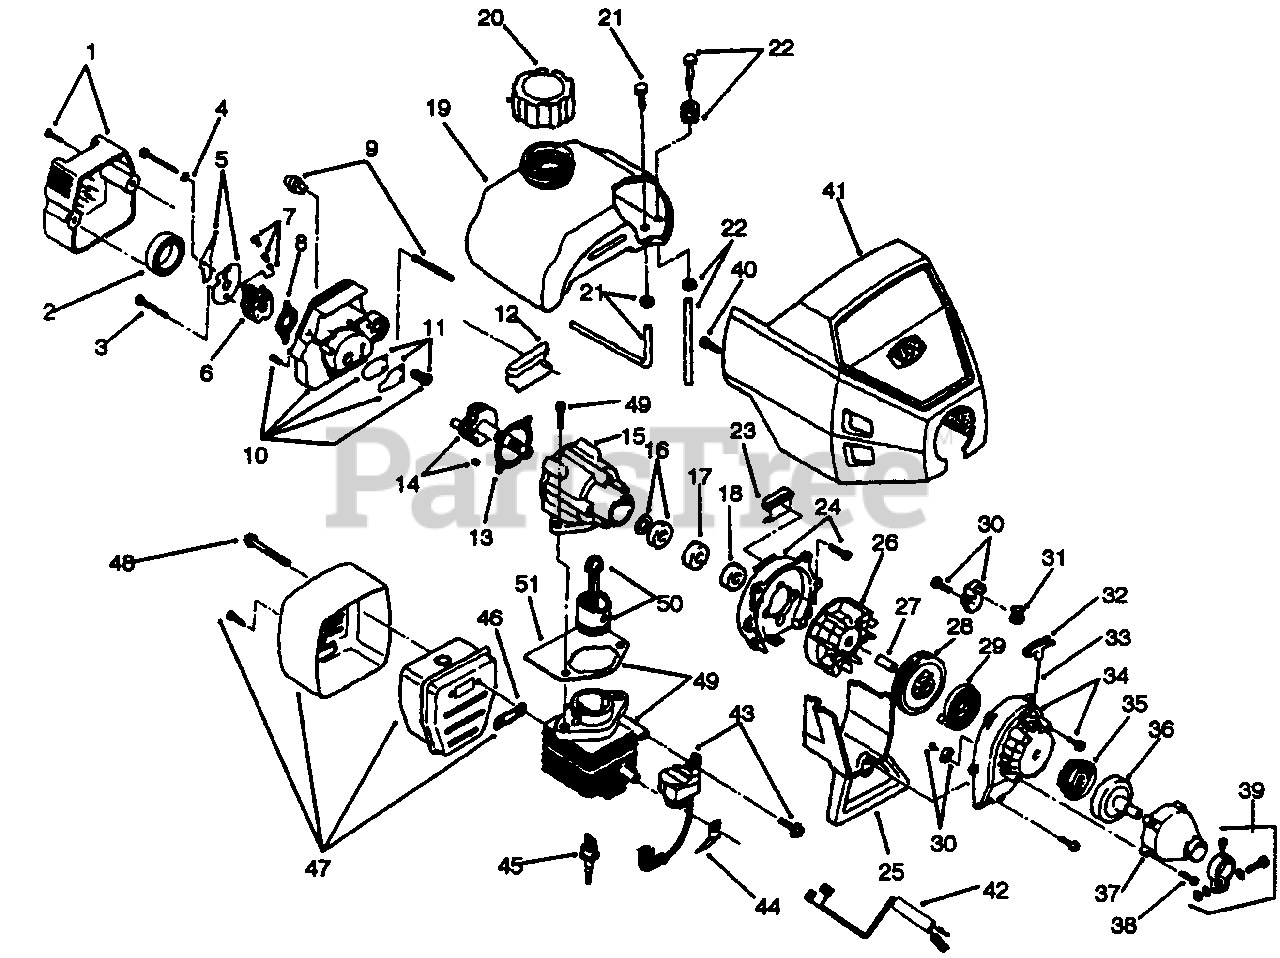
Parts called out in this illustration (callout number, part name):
1	Assy.-Carburetor/Air Clean (Inc. Ref. No.2)
2	Filter-Air Cleaner
3	Screw-Carburetor
4	Washer-Wave
5	Choke-Lever and Plate
6	Assembly-Carburetor
7	Throttle Adj.-Walbro
8	Gasket-Carb. (10 Pack)
9	Assy.-Primer and Hose
10	Assembly-Carb. Mount (Incl. Ref. No. 11 & 13)
11	Assembly-Reed
12	Pad-Mounting Rear
13	Gasket (10 Pack)
14	Assembly-Power Shaft
15	Assy.-Crankcase (Incl. Ref. No. 14-18)
16	Assembly-Inner Bearing
18	Assembly-Outer Bearing
19	Assembly-Fuel Tank (Incl. Ref. No. 20-22)
20	Assembly-Fuel Cap
21	Assembly-Return Line
22	Assembly-Fuel Line
23	Pad-Mounting, Front
24	Assembly-Shroud
25	Shroud Extension & Stand
26	Assembly-Flywheel
28	Assembly-Recoil Pulley
29	Spring-Recoil
30	Assembly-Pulley Retainer
31	Guide-Rope
32	Handle-Pull
34	Assembly-Starter Housing
35	Assembly-Clutch Rotor
36	Assembly-Clutch Drum
37	Assembly-Clutch Cover
38	Screw-Clutch Cover
39	Assembly-Clamp
40	Screws-Engine Cover
41	Assembly-Engine Cover
42	Assembly-Lead Wire
43	Assembly-Module
44	Tab-Ground
45	Spark Plug
46	Gasket-Exhaust (10 Pack)
47	Assembly-Muffler
48	Bolt-Muffler
49	Assembly-Cylinder (Incl. Ref. No. 51)
50	Assy. Piston & Rod
51	Gasket-Cylinder (10 Pack)
